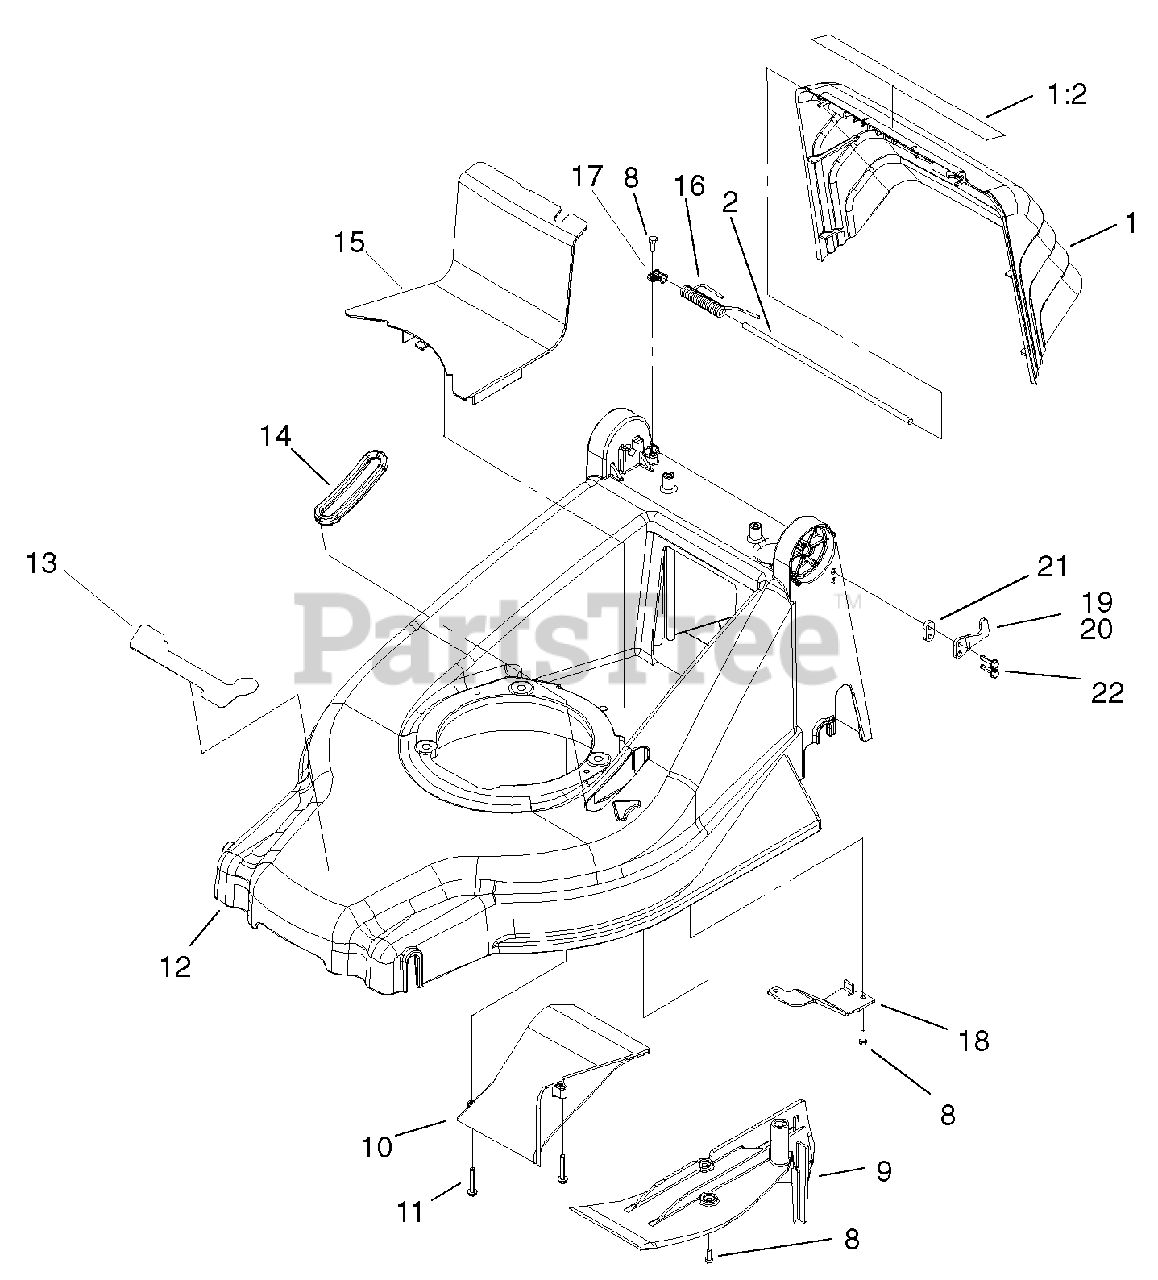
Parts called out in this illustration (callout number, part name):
1:2	Decal-Danger
2	Rod-Pivot, Door
8	Screw-Taptite
9	Kicker-Cover, Rear
10	Ramp-Discharge
11	Screw-HWH
13	Decal-Deck
15	Belt Cover
16	Spring-Torsion, Door
18	Bracket-Deck
19	Hook-Left
20	Hook-Right
22	Screw-HWH
